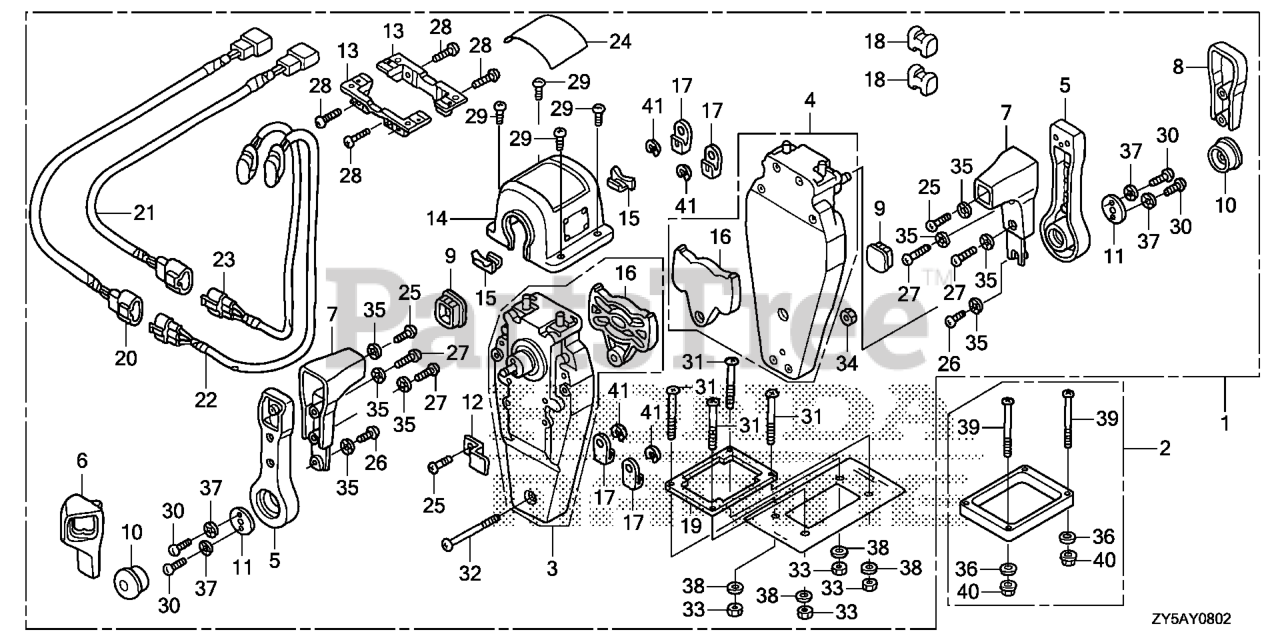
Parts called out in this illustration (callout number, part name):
1	BOX KIT, R. REMOTE CONTROL (TOP MOUNT DUAL)
1	BOX KIT
2	SPACER KIT, REMOTE CONTROL BOX (TOP MOUNT DUAL)
3	HOUSING ASSY., L. (INNER) (TOP MOUNT)
4	HOUSING ASSY., R. (INNER) (TOP MOUNT)
5	HANDLE, REMOTE CONTROL
6	COVER, L. GRIP
7	GRIP, REMOTE CONTROL HANDLE
8	COVER, DUAL GRIP
9	CAP, GRIP
10	BUTTON, THROTTLE
11	PLATE, HANDLE
12	PLATE, CABLE CLAMP
13	BRACKET, REMOTE CONTROL HOUSING
14	HOUSING, DUAL REMOTE CONTROL BOX
15	HOUSING, LEAD
16	PLATE, DWELL
17	TERMINAL, CABLE
18	SPACER, CABLE CLAMP
19	GASKET, DUAL
20	SUB-HARNESS ASSY., POWER TRIM-TILT (A)
21	SUB-HARNESS ASSY., POWER TRIM-TILT (B)
22	SWITCH ASSY., POWER TRIM-TILT (A)
23	SWITCH ASSY., POWER TRIM-TILT
24	MARK, REMOTE CONTROL (DUAL)
25	SCREW, PAN (5X16)
26	SCREW, PAN (5X10)
27	SCREW, PAN (5X20)
28	SCREW, PAN (5X18)
29	SCREW, PAN (4X10)
30	SCREW, PAN (6X18)
31	SCREW, PAN (5X40)
32	SCREW, PAN (5X55)
33	NUT, HEX. (5MM)
34	NUT, HEX. (5MM)
35	WASHER, LOCK (5MM)
36	WASHER, PLAIN (5MM)
37	WASHER, LOCK (6MM)
38	WASHER, PLAIN (5MM)
39	SCREW, PAN (5X65)
40	NUT, HEX. (5MM)
41	E-RING (6MM)
